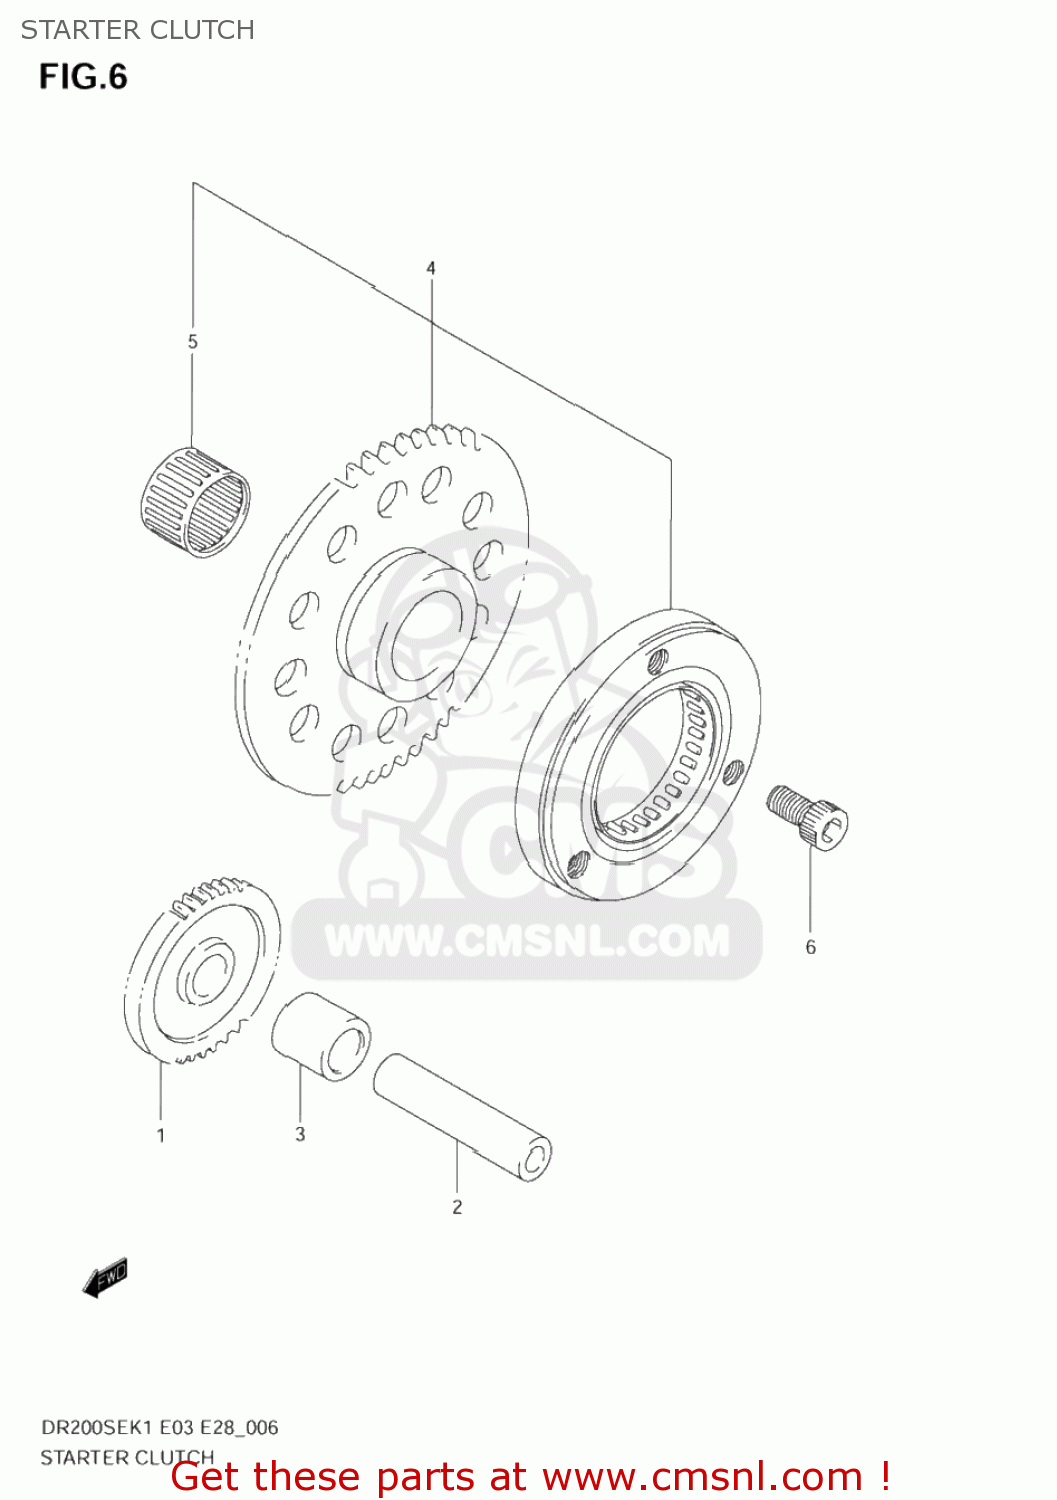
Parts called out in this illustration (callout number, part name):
1	GEAR,STARTER,IDLE
2	PIN(7.4X13X56)
3	SPACER(13X19X19)
4	CLUTCH SET,STARTER
5	BEARING(22X28X16)
6	BOLT
